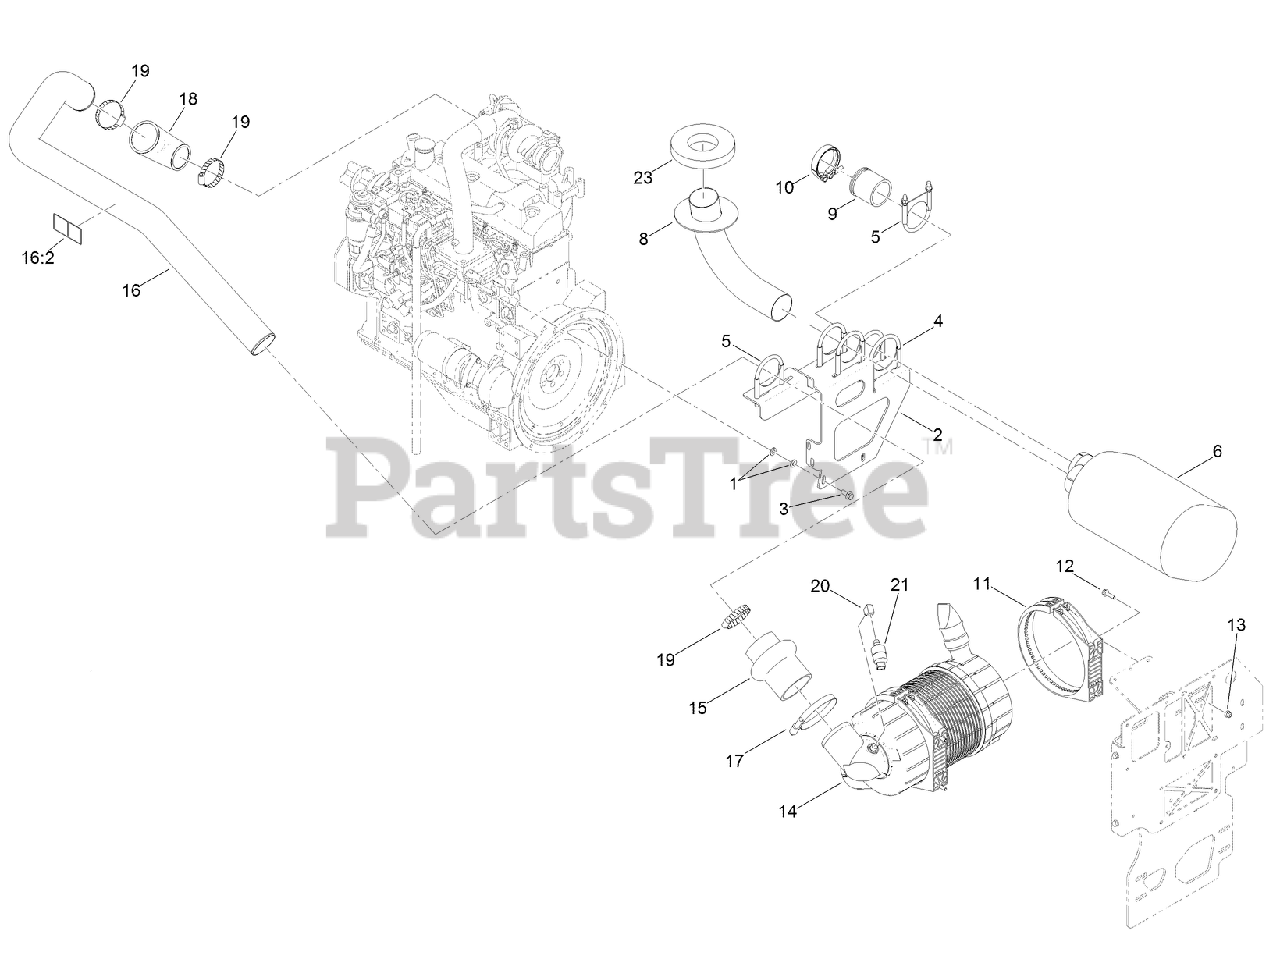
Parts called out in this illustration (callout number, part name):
1	WASHER-FLAT
2	BRACKET-MOUNT, MUFFLER
3	SCREW-HHF
4	CLAMP-GUILLOTINE
5	CLAMP-GUILLOTINE
6	MUFFLER
8	TUBE-EXHAUST (W/ SEAL PLATE)
9	FLANGE-ADAPTER, TURBO
11	BAND-MOUNTING, AIR CLEANER
12	SCREW-HHF
13	NUT-LOCK, HHF
14	AIR CLEANER ASM
15	REDUCER-HOSE
16	AIR INTAKE ASM
16:2	DECAL-WARNING, HOT SURFACE
17	CLAMP-TORQUE, CONSTANT
18	ELBOW-90 DEG
19	CLAMP-HOSE
20	FITTING-ELBOW, 90
21	SWITCH ASM
23	INSULATION
